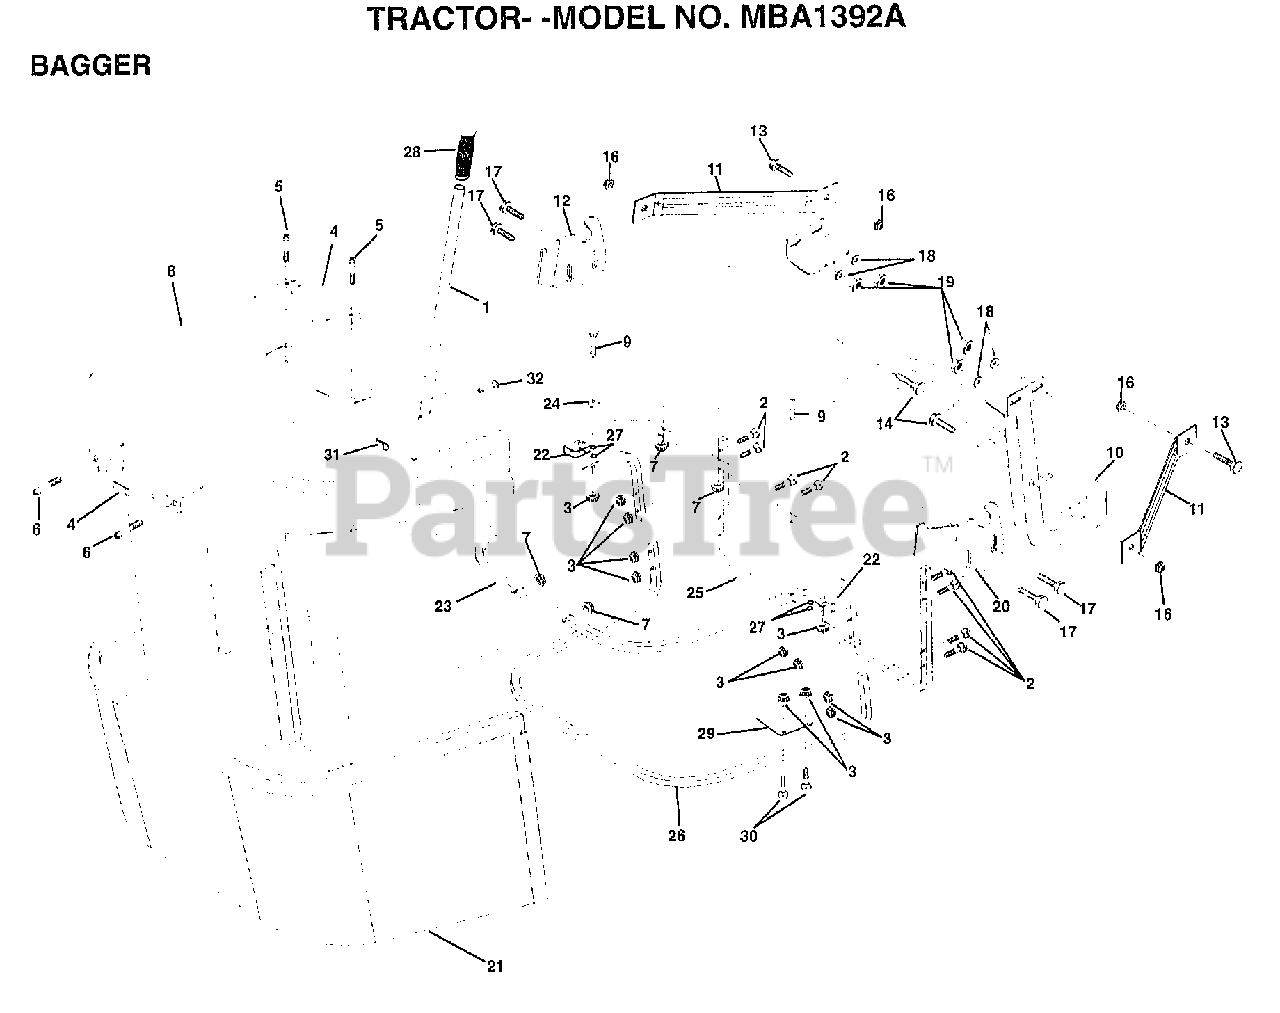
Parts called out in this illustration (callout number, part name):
1	TUBE.HDLE.BAG.CRD
2	BOLT.CARRIAGE.1/4-20X2.0
4	HANDLE.GRAB.BLACK.
5	"SCREW,PAN.HEAD"
8	COVER.BAG.PLASTIC.CRD
9	BOLT CARRIAGE
10	SUPT.ASM.WLDMNT.BAG.CRD
11	BRKT.SUPT.UPPER.BAG.CRD
12	BRKT.PIVOT.BAG.LH.CRD
13	BOLT
14	BOLT.HEX.3/8-16X2-1/2
17	BOLT
18	WASHER
19	NUT
20	"BRKT.PIVOT.BAG,RH.CRD"
21	BAG.ASM.CRD
22	BRKT.SIDE.BAG.CRD
23	TUBE.UPPER.BAG.CRD
24	TUBE.PIVOT.BAG.CRD
25	TUBE.FT.BAG.CRD
26	TUBE.LOWER.BAG.CRD.
27	GROMMET.EXTRUDED
28	GRIP.HANDLE.BLACK
29	PLATE.STOP.BAG.HDLE.CRD
30	BOLT.CARRIAGE
31	RETAINER M
32	RIVET.DRILL.1.75
33	"BRKT.PIVOT.BAG,RH.CRD"
